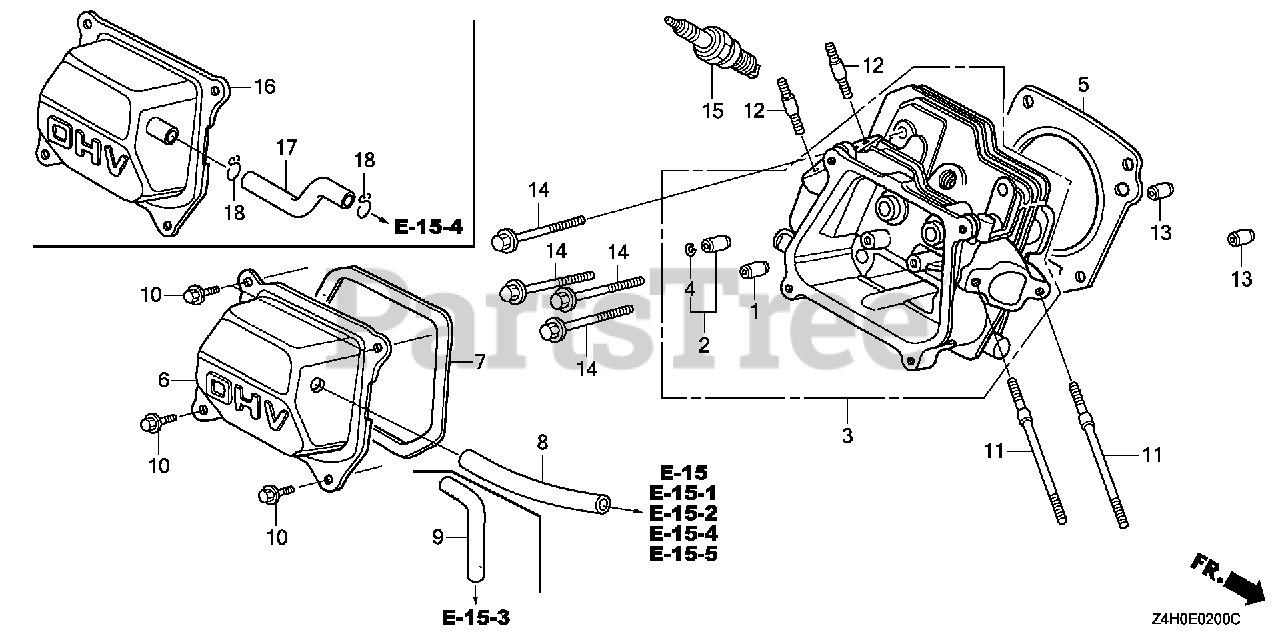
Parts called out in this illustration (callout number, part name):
1	GUIDE, VALVE (OVER SIZE)
2	GUIDE, EX. VALVE (OVER SIZE)
3	CYLINDER HEAD
4	CLIP, VALVE GUIDE
5	GASKET, CYLINDER HEAD (THAI LEAKLESS)
6	COVER, HEAD
7	GASKET, HEAD COVER
8	TUBE, BREATHER
10	BOLT, FLANGE (6X12) (CT200)
11	BOLT, STUD (6X114)
12	BOLT, STUD (8X32)
13	PIN, DOWEL (10X16)
14	BOLT, FLANGE (8X55)
15	SPARK PLUG (BPR6ES) (NGK)
15	SPARK PLUG (W20EPR-U) (DENSO)
